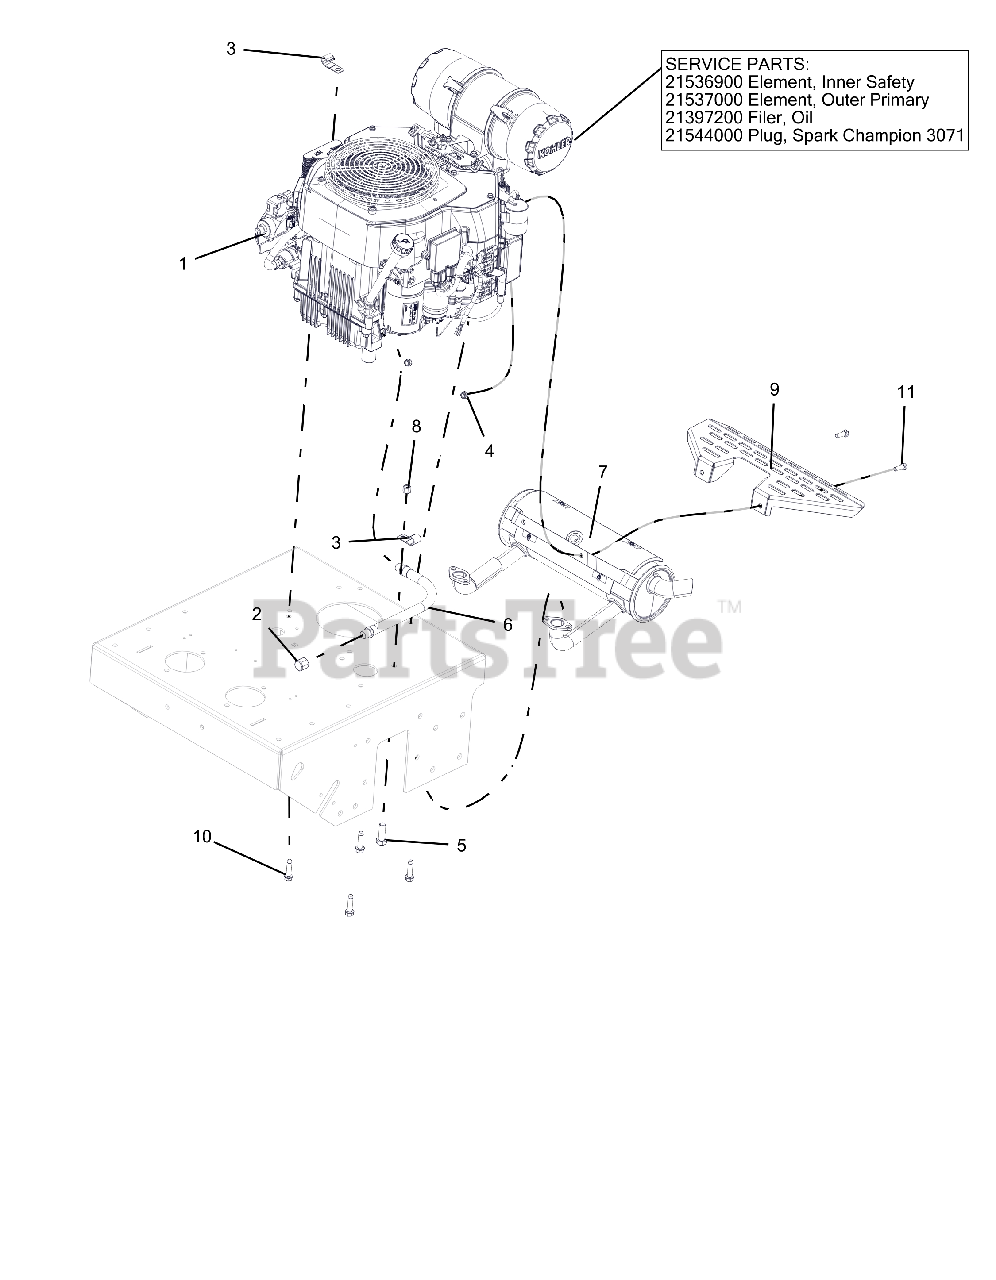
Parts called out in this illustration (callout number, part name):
1	ENGINE, KOHLER PVC680 EFI LP
2	PIPE, CAP 3/8 NPT FEMALE
3	P-CLIP, .500 INSULATED
4	NUT-LK-NYL .312-18 YWZC
5	BLT-HEX .50-13X1.50 GR5 YWZC
6	HOSE, HYD .38-11-OK M6N0-M6N0
7	MFLR, KOHLER
8	NUT-LK-NYL .38-16 YWZC
9	GUARD, HEAT SHIELD
10	SCR-TAP .38-16X1.50 HWH TR YZ
11	BLT-HEX .31-18X1.00 GR5 YWZC
12	ELEMENT, INNER SAFETY
13	ELEMENT, OUTER PRIMARY
14	FILTER, OIL
15	PLUG, SPARK CHAMPION 3071
